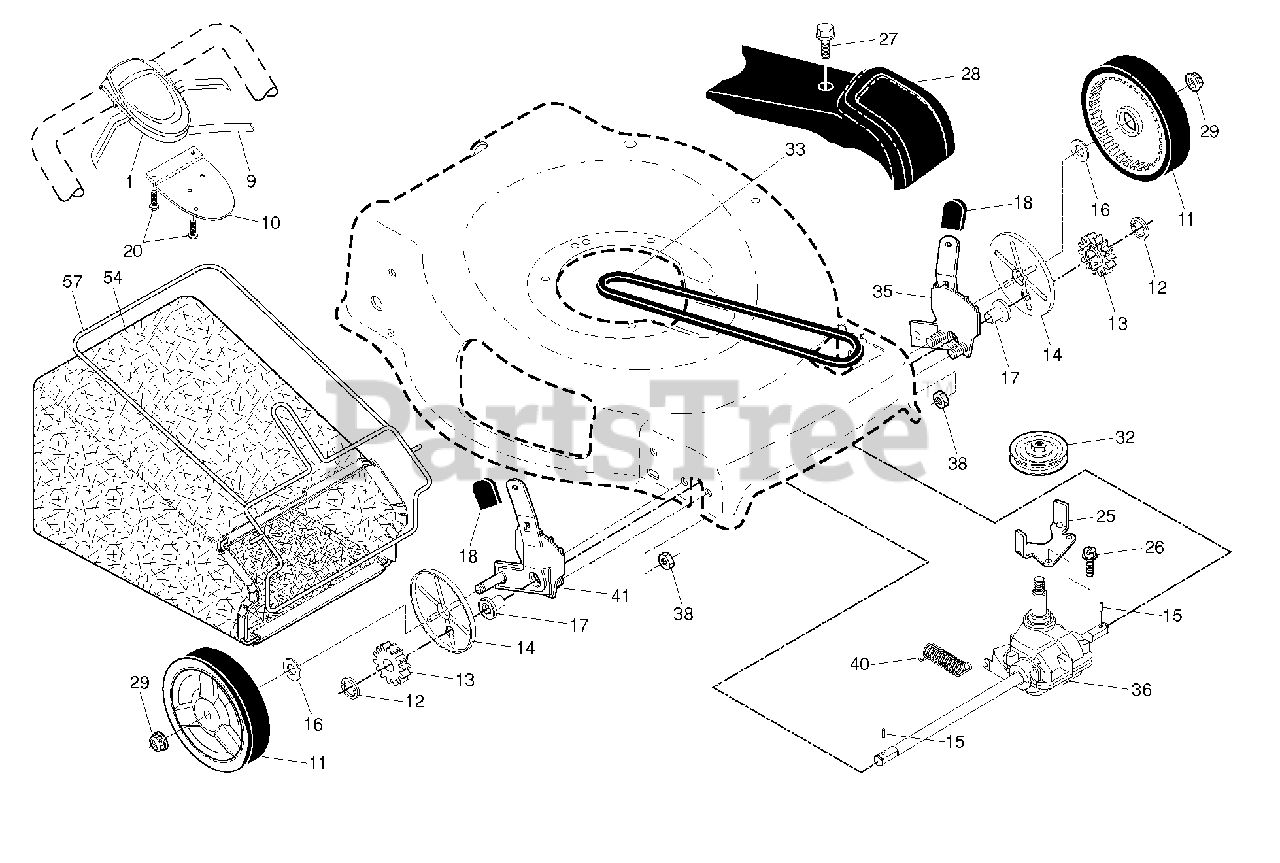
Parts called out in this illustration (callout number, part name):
9	CABLE.CONTROL.22FGD.GEN2
10	BRACKET.DRIVE.CONTR.GEN2.BLACK
11	WHEEL.8X1.75.H3SPK.RAD3.GY.BU3
12	E-RING 7/16 RE
13	PINION.14.TEETH.FGD
14	COVER.DUST.WHEEL
15	PAWL, DRIVE
16	WASHER FLUT
17	RP BEARING.ASM.
18	SELECTOR KNOB
20	SCREW, PHILLIPS HEAD 10 X 5/8
25	BRACKET.BELT.GUIDE.22+FGD.BZP
27	SCREW, HEX HD TAPPING #10-24 1
28	COVER.DRIVE.22.LABEL.HUSQVARNA
29	NUT.HEX.FLANGE.3/8-16.LO(3 2)
32	RP PULLEY.DRIVE.EZ
33	BELT.DRIVE.FWD.
35	ADJUSTER.ASM.9.22+/RF/LR.21/RF
36	TRANSMISSION.22PLUS.FGD.AW2/EZ
38	NUT.HEX.FLANGE.1/4
41	ADJUSTER.ASM.9.22+/RF/LR.21/LF
54	GBAG.A3610247T.SILV.HUSWT.BLUE
57	RB FRAME.GBAG.22PLUS
